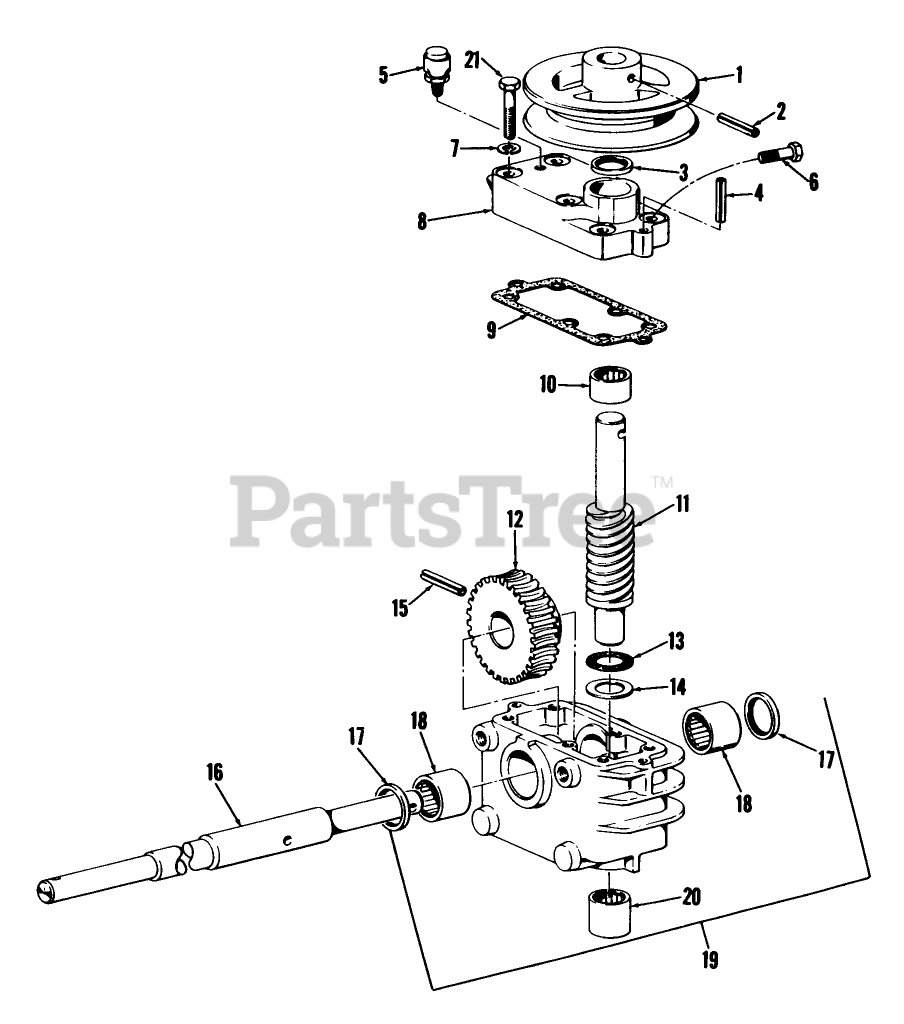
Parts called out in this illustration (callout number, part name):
1	SCREW-HH
2	CHOKE CONTROL
6	SCREW-HHFTF
7	TIE-CABLE
10	SWITCH
11	THROTTLE CONTROL
12	WASHER-FLAT
13	NUT-HEX
14	NUT-LOCK, NI
15	WASHER
16	ENGINE RUBBER MT
17	SHIM-AXLE
18	WASHER-FLAT
19	SCREW-HH
20	NUT-LOCK, NI
21	SCREW-HH
23	NUT-LOCK, NI
24	NUT-JAM
25	RUBBER MOUNT
27	SCREW-HSBH
28	NUT-LOCK, NI
29	BATT BOX FOAM
31	SCREW-HHF
32	Battery Assy.
34	NUT-HHF, WHIZ
35	SCREW-CARR
36	DECAL-OIL
37	HOUR METER
38	BRACKET
39	WASHER-LOCK, INT
40	NON SKID (TUNNEL)
41	SCREW-HH
42	SCREW-HH
44	NON-SKID-FLOOR
46	WASHER-LOCK
47	FRAME ASM
48	SCREW-HH
49	NUT-LOCK, NI
51	SCREW-HWH
52	NUT-HEX
53	NUT-HEX
54	WASHER-LOCK
55	WASHER-FLAT
56	MTG CLAMP F/W GUAGE
58	SCREW-HWHTF
59	BOOT-SWITCH
60	BY-PASS DECAL
61	SWITCH & BOOT ASM
63	WASHER-LOCK
64	SCREW-HH
